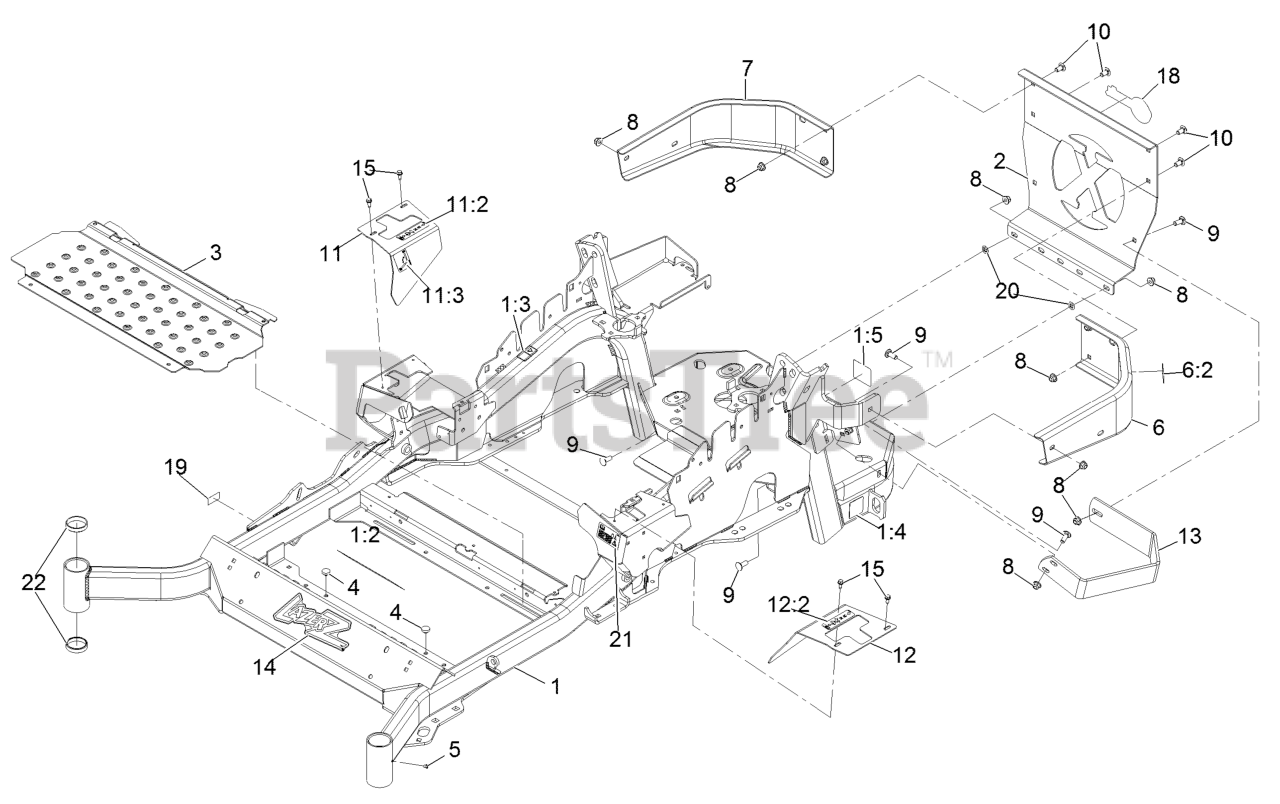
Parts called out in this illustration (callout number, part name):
1	MAINFRAME ASM
1:2	DECAL-WARNING, SLOPE
1:3	DECAL-WARNING
1:4	DECAL-HAZARD, PINCHED FINGER
1:5	DECAL-SPARK ARRESTER
2	PLATE,REAR GUARD
6	LH BUMPER ASM
6:2	DECAL-WARNING
7	BUMPER-RH
8	NUT-HF, NI
9	SCREW-CARR
10	SCREW-CARR
11	RH MOTION CONTROL COVER ASM
11:2	DECAL-CONTROL, MOTION
11:3	DECAL-PARK BRAKE, CE
12	LH MOTION CONTROL COVER ASM
12:2	DECAL-CONTROL, MOTION
13	GUARD-MUFFLER
14	DECAL,LAZER MODEL
15	SCREW-HWH
19	Decal-Patent Ttco.Com
20	NUT-PUSH
21	DECAL-FUEL FILL, CE
22	CUP-BEARING
